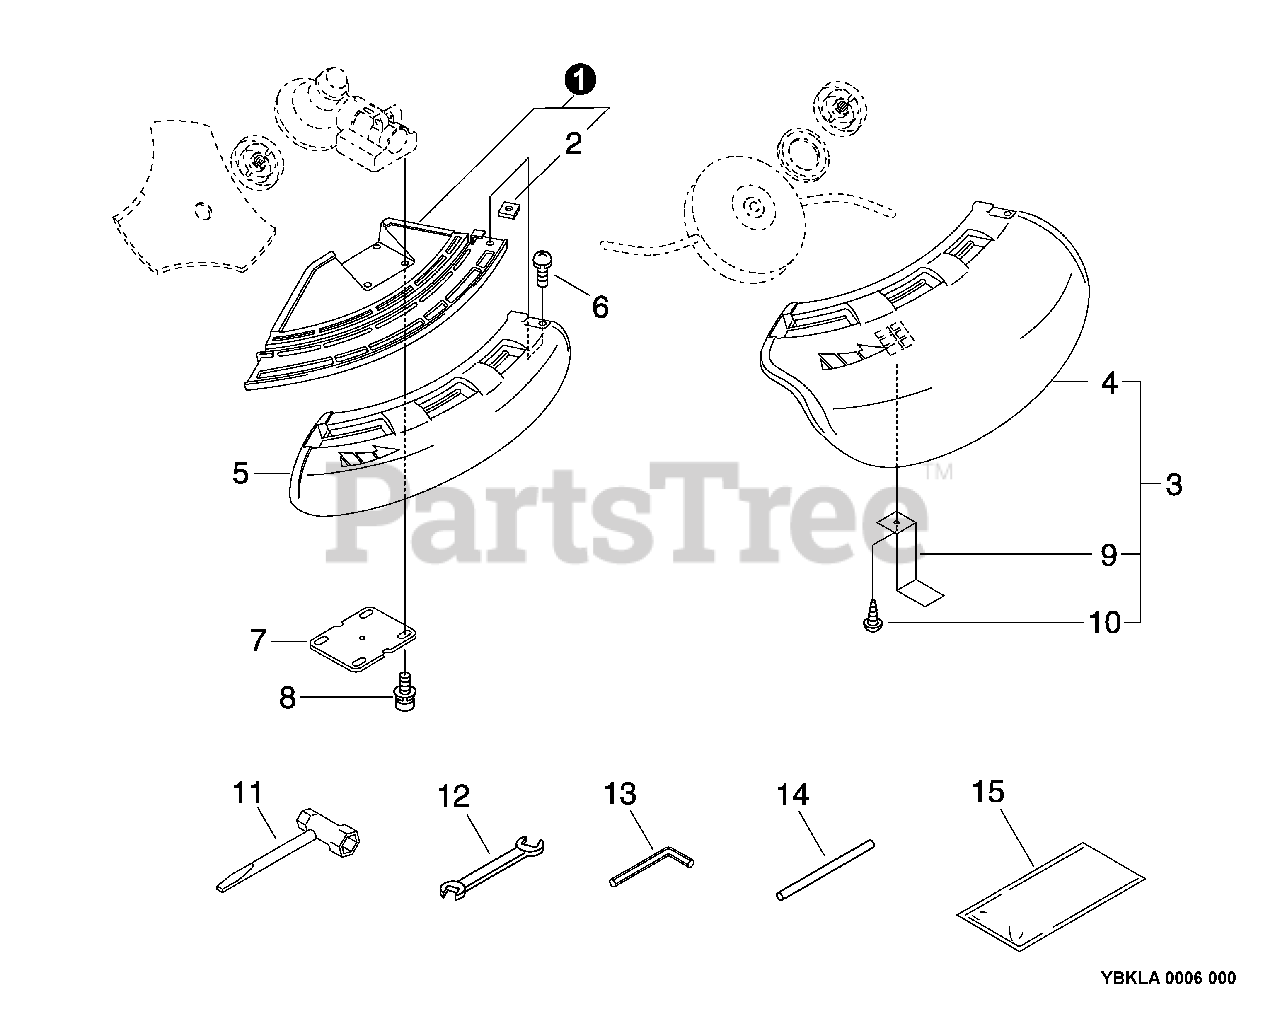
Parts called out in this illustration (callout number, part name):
1	DEBRIS SHIELD KIT
2	NUT - 5 -- SQUARE
3	DEBRIS SHIELD KIT
4	SHIELD, DEBRIS - TRIMMER
5	SHIELD, DEBRIS - BLADE
6	SCREW - 5X22
9	KNIFE, TRIMMER LINE
10	SCREW - 5X12
11	T-WRENCH - 17X19mm
12	SPANNER - 8X10mm
13	HEX KEY - 4mm
14	ROD, LOCKING - 5X120mm
15	BAG, TOOL
